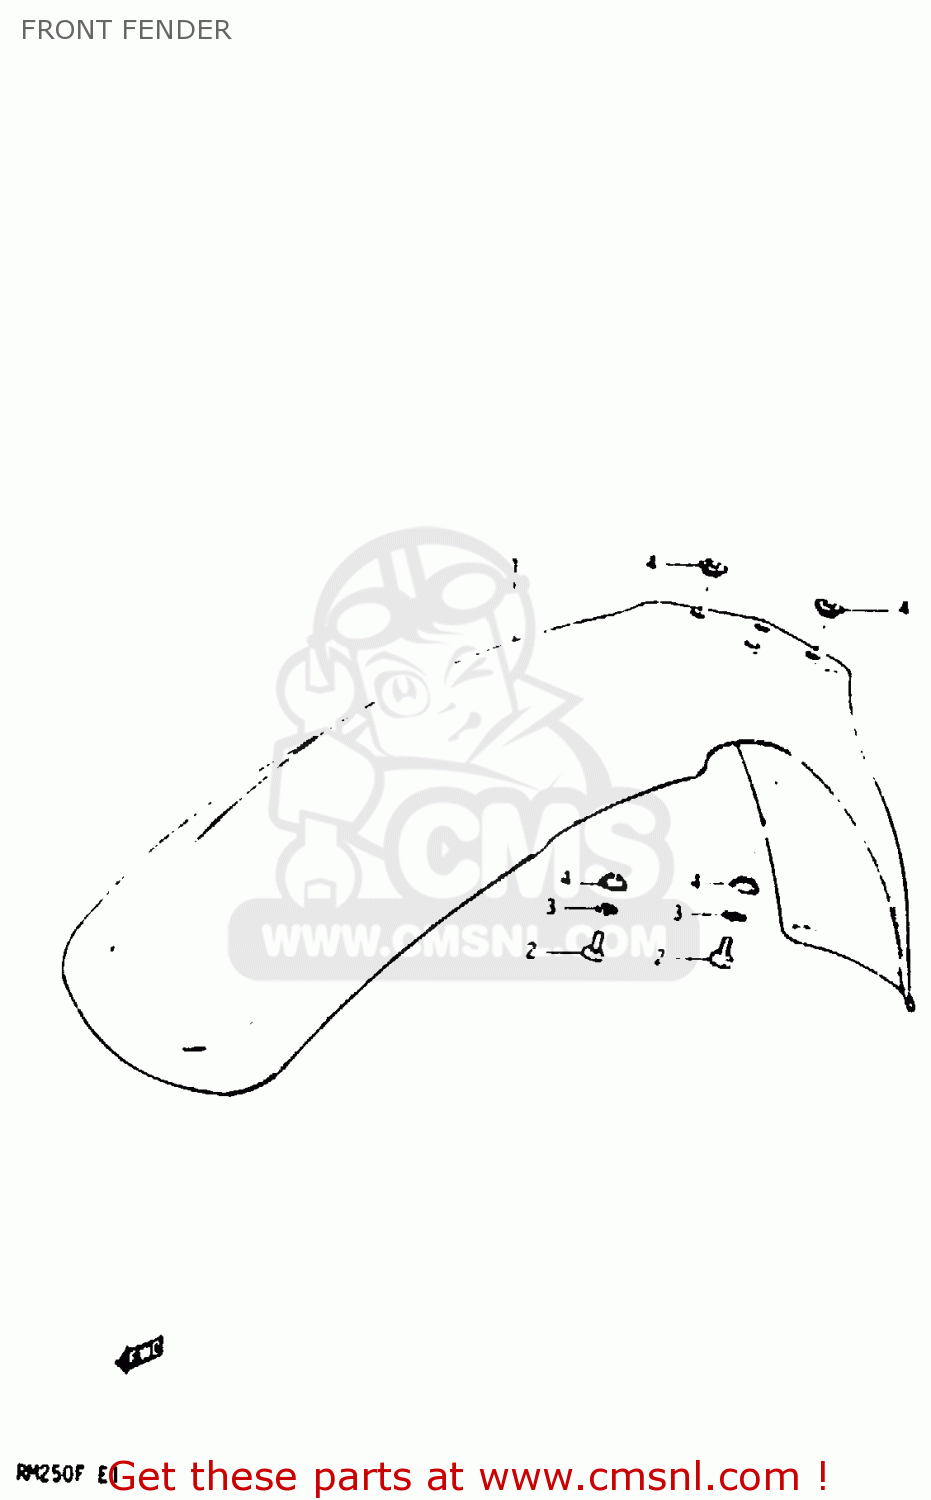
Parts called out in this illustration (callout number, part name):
1	FENDER,FRONT
2	BOLT, UPPER
3	LOCK WASHER
4	SPACER
